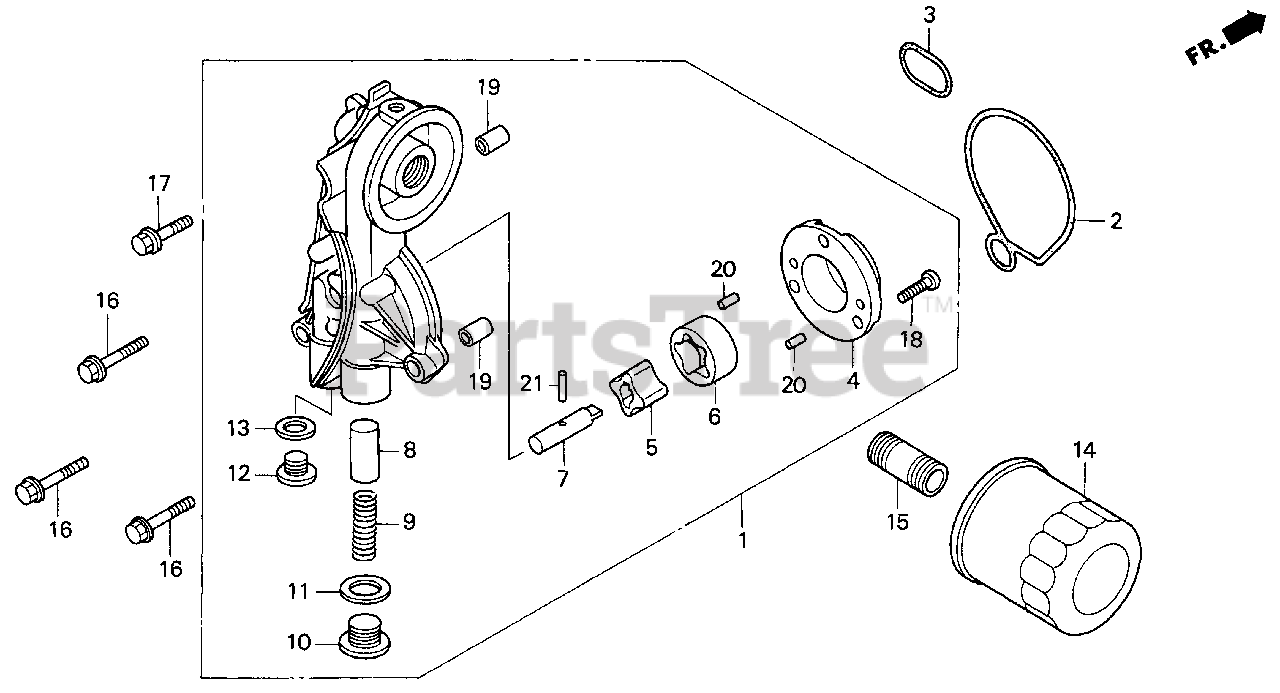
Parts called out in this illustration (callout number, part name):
1	PUMP ASSY., OIL
2	GASKET, OIL PUMP
3	GASKET, OIL PUMP (B)
4	COVER, OIL PUMP
5	ROTOR, OIL PUMP (INNER)
6	ROTOR, OIL PUMP (OUTER)
7	SHAFT, OIL PUMP
8	VALVE, RELIEF
9	SPRING, RELIEF VALVE
10	BOLT, SEALING (18MM)
11	WASHER, SEALING (18MM)
12	BOLT, SEALING (14MM)
13	WASHER, SEALING (14MM)
14	FILTER, OIL
14	FILTER, OIL (TOYO ROKI)
15	HOLDER, OIL FILTER
16	BOLT, FLANGE (6X32)
17	BOLT, FLANGE (6X25)
18	SCREW, PAN (6X14)
19	PIN A, DOWEL (8X14)
20	PIN, DOWEL (5X8)
21	ROLLER (3X15.8)
